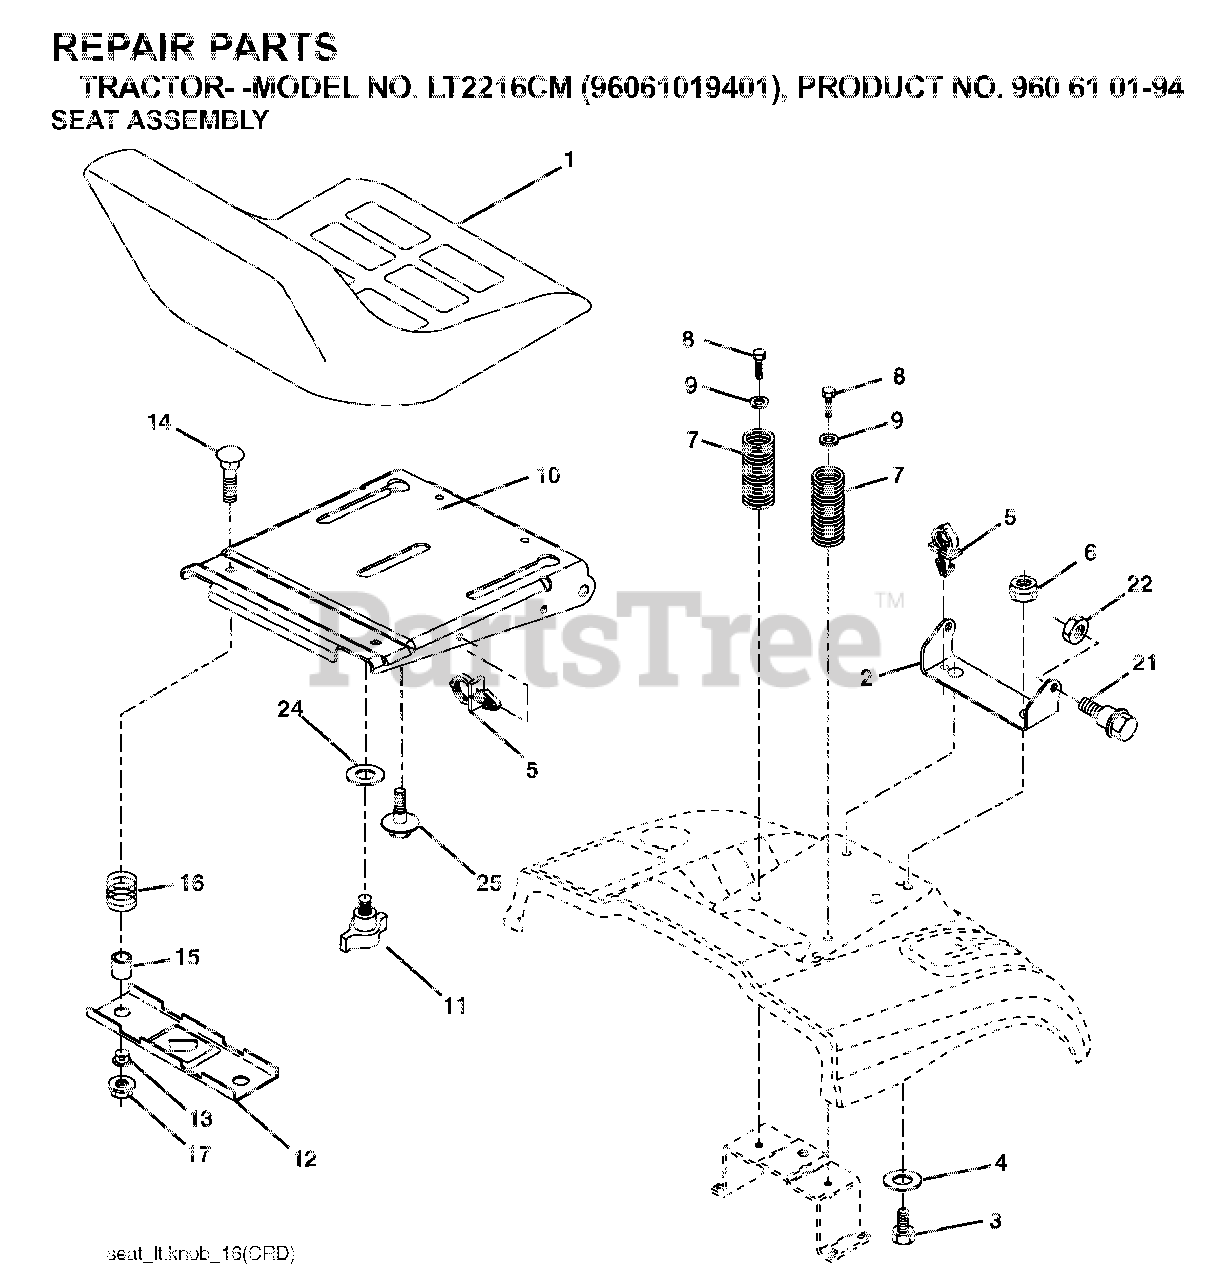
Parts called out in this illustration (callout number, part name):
2	SEAT PIVOT BRKT
4	WASHER PM
5	PUSH CLIP
6	NUT
7	SPRING COMPRESSION
8	SCREW 3/8-16X1
9	WASHER
10	PAN.ASM.SEAT.1SLOT
11	KNOB.SEAT.ADJ.WINGNUT
12	BRKT.MNTNG.SWITCH.SEAT
14	BOLT.ROUND.HEAD.SQUARE.NECK
15	SPACER SPLIT 28X.96
17	NUT T
21	BOLT.SHOULDER.5/16-18
22	NUT.71038.31-18.HEX.NYLOCK
25	BOLT,SHOULD
